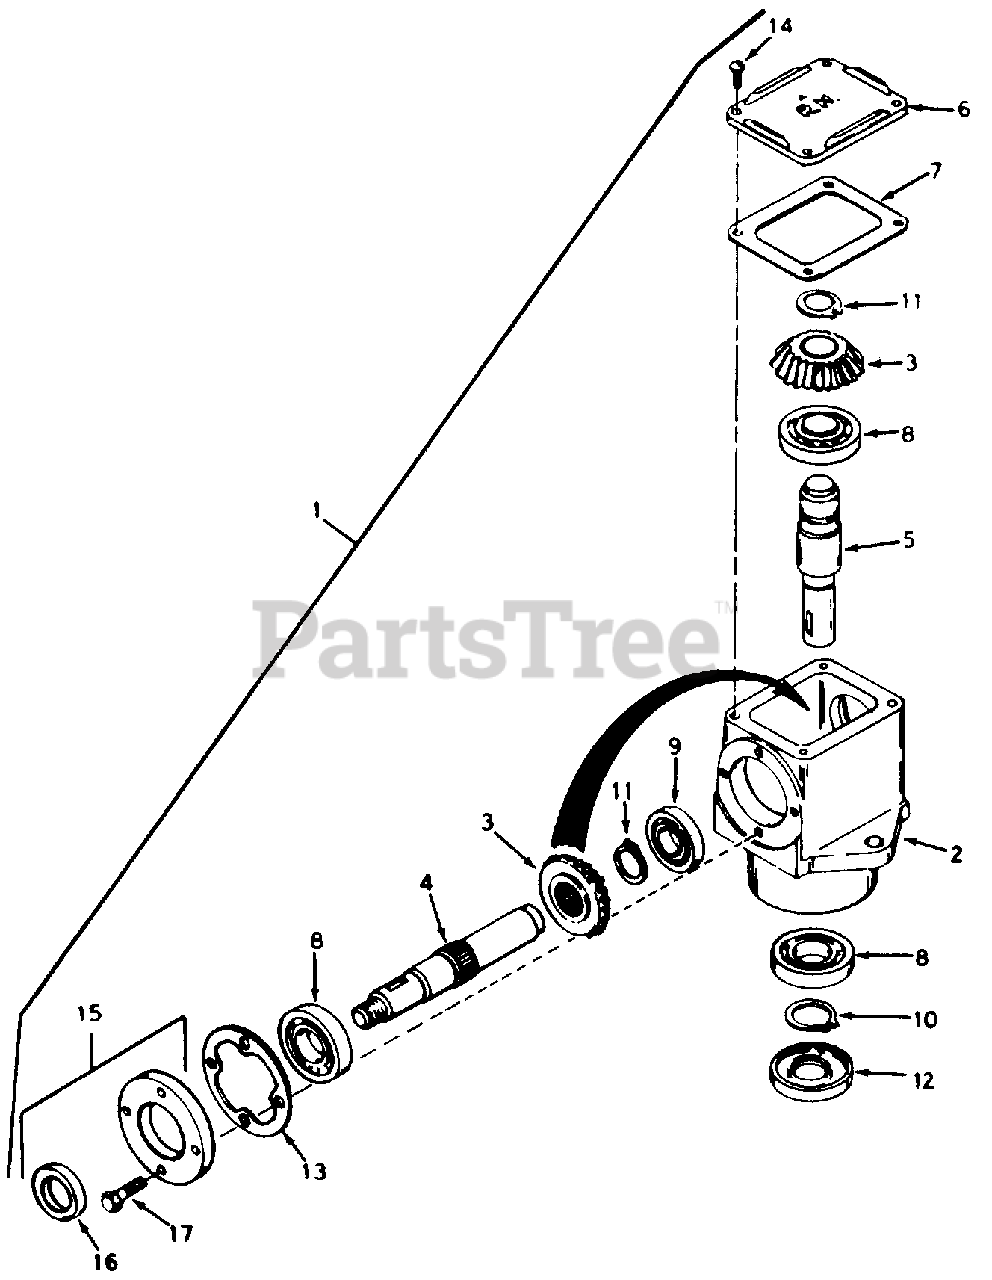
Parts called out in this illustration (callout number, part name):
1	Head Ass'y. R.H.
2	Housing, Right Angle Drive
3	Gear, Miter
4	Shaft, Input
5	Shaft, Output
6	Cover, Right Hand
7	Gasket, Cover
8	Bearing, Ball
9	Bearing, Ball
10	Ring, Snap
11	Ring, Snap
12	Seal, Oil
13	Gasket, Cap
14	Screw, Rd. Hd. Self-Tap. 10-24 x 1/2
15	Cap & Seal Ass'y., Retainer
16	Seal, Oil
17	Screw, Hex Hd. 1/4-20 x 7/8
